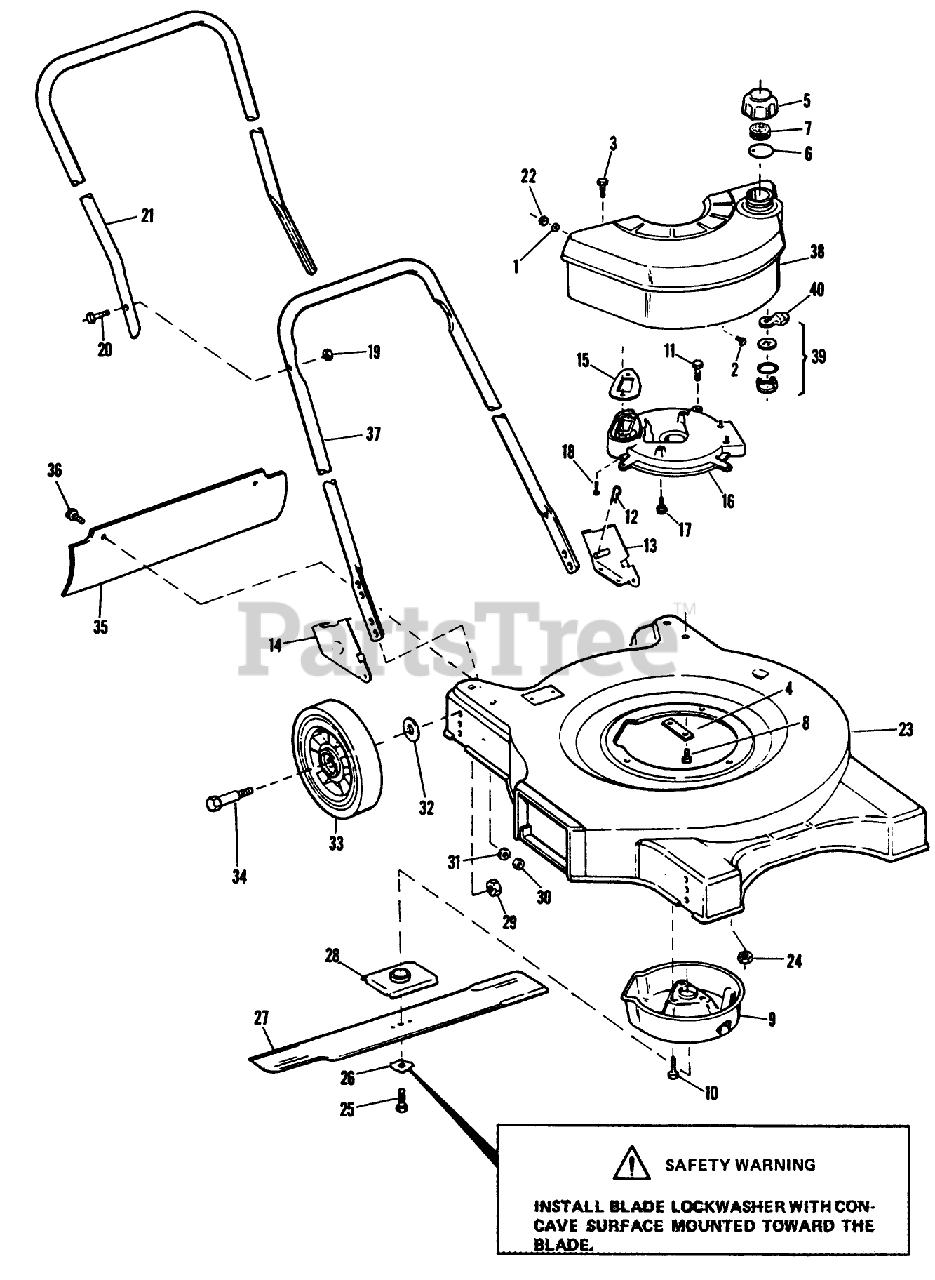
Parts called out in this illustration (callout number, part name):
3	SCREW F
6	GASKET S
7	BAFFLE - FOAM SM
8	SCREW
12	HAIR PIN
16	PLATE,MUFFLER F
18	SCREW V
19	LOCKNUT E
24	NUT-LOCK F
26	LOCKWASHER
29	LOCKNUT
30	LOCKNUT E
32	WASHER WROUGHT
39	SHUT OFF VALVE KIT
